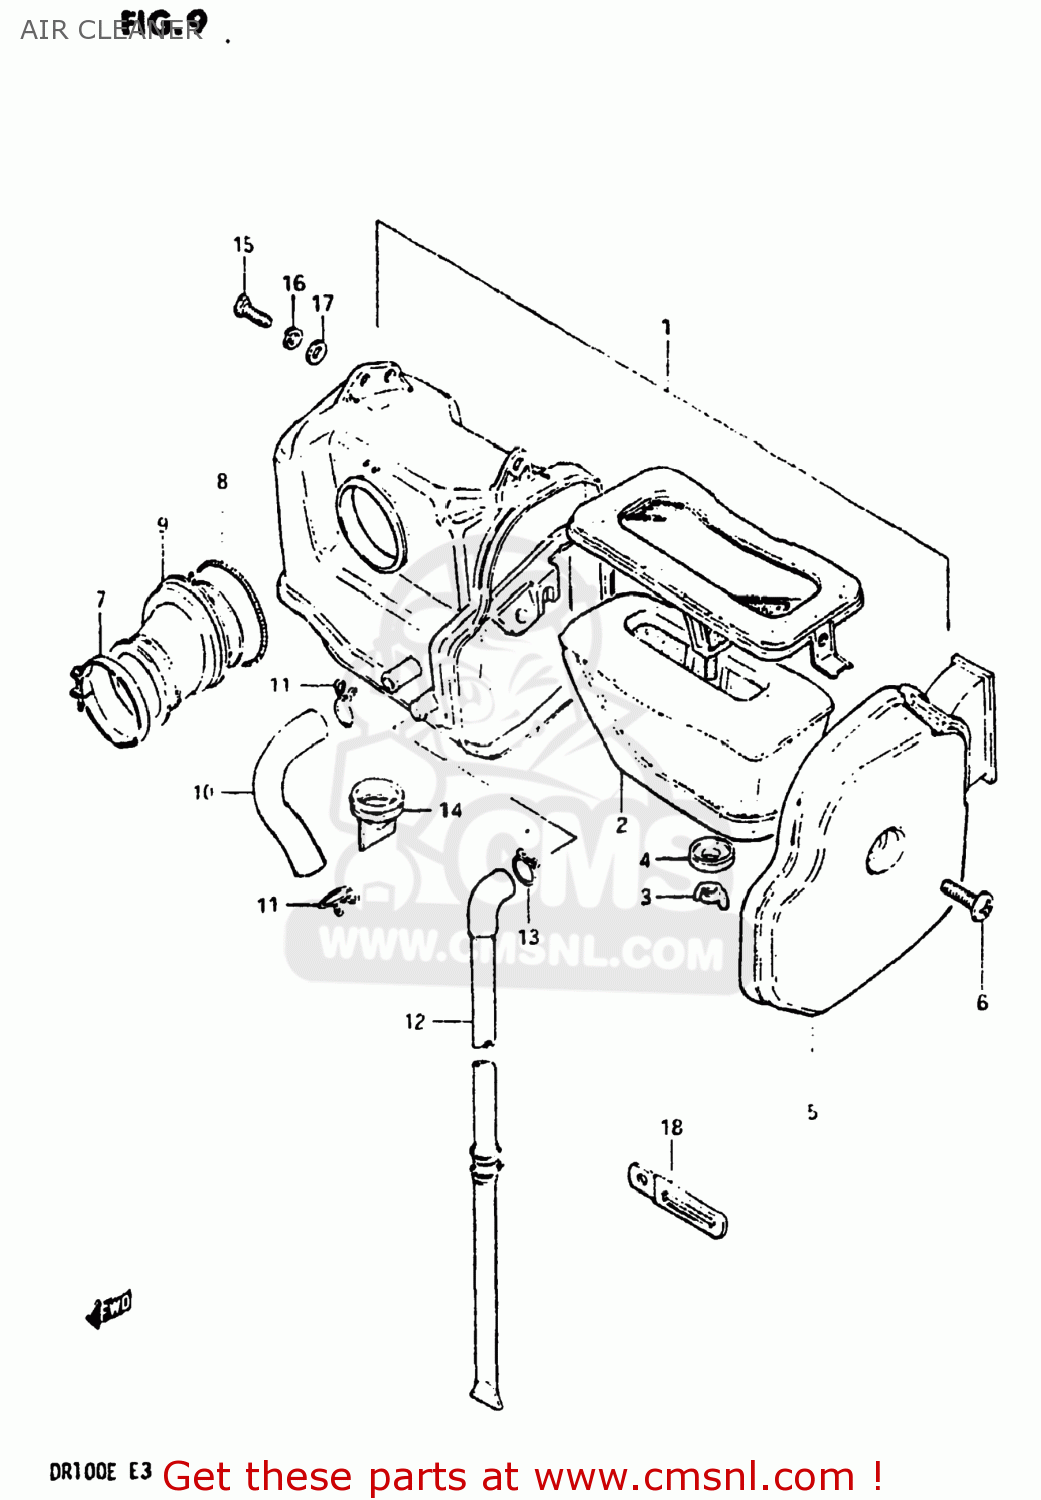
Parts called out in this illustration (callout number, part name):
1	CLEANER ASSEMBLY,AIR
2	ELEMENT,AIR CLEANER
3	NUT
4	WASHER
5	CAP,AIR CLEANER
6	SCREW, COVER SIDE
7	CLAMP
8	CLAMP,CLEANER SIDE
9	TUBE,OUTLET
10	TUBE,AIR CLEANER BREATER
11	CLAMP
12	HOSE,AIR CLEANER DRAIN
13	CLAMP
14	DRAIN TUBE
15	BOLT, UPPER
16	LOCK WASHER
17	WASHER
18	CLAMP
